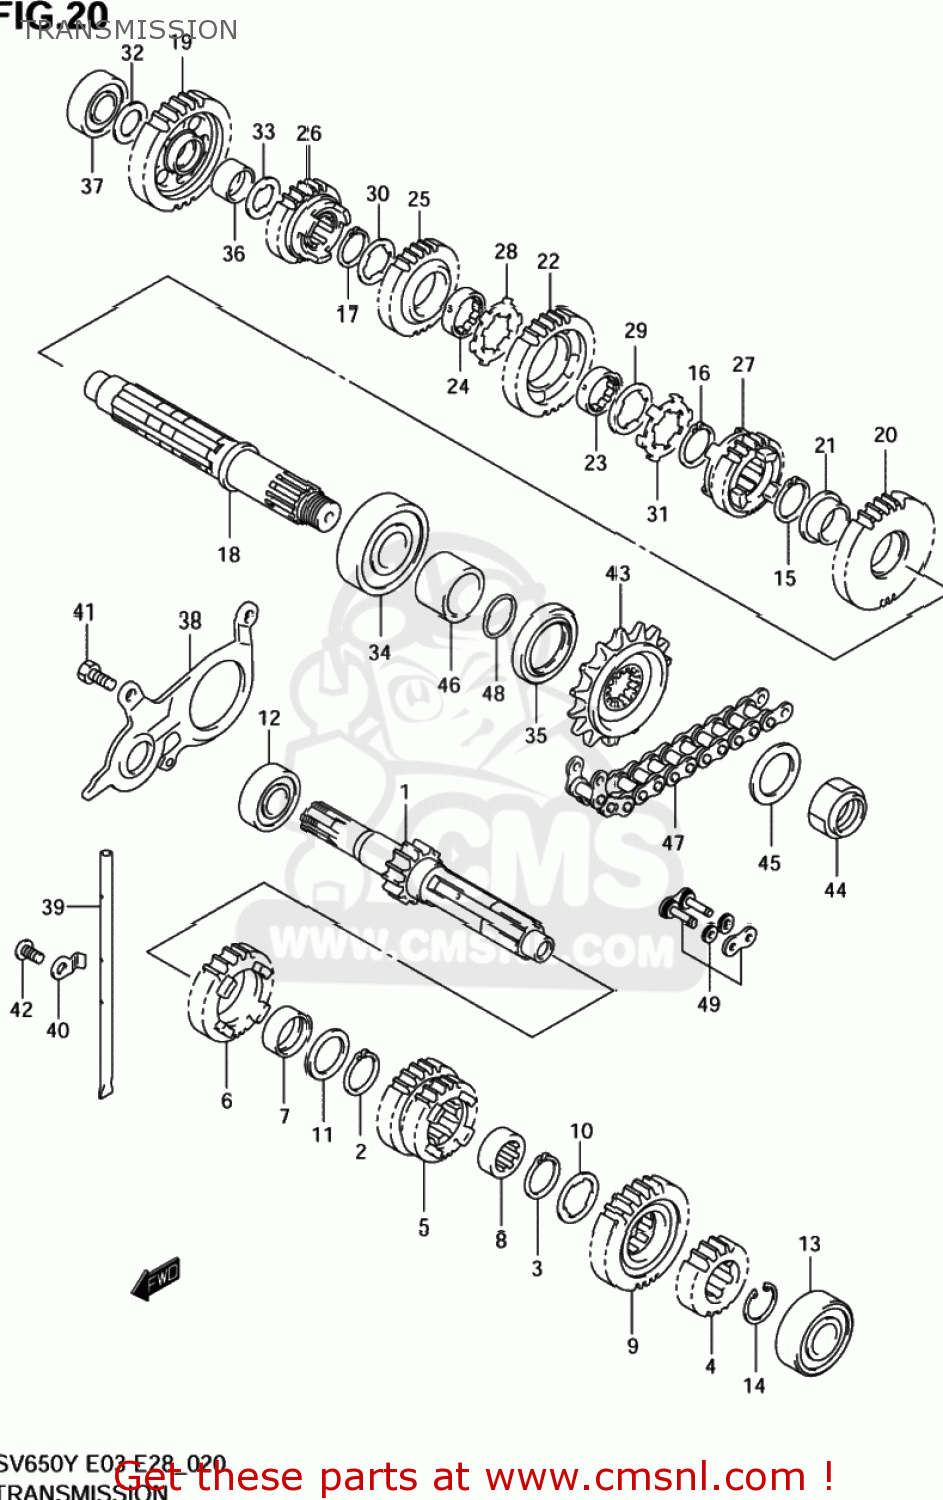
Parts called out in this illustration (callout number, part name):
1	SHAFT,COUNTER(NT:13)
2	CIRCLIP
3	CIRCLIP
4	GEAR,SECOND DRIVE (NT:18)
5	GEAR,3RD & 4TH
6	GEAR,FIFTH DRIVE (NT:26)
7	BUSH
8	BUSH,6TH DRIVE GEAR
9	GEAR,6TH DRIVE(NT:27)
10	WASHER,LOCK
11	SHIM(25X34X1)
12	BEARING(17X40X12)
13	BEARING 20X52X15
14	CIRCLIP
15	CIRCLIP
16	CIRCLIP
17	CIRCLIP
18	SHAFT,DRIVE
19	GEAR,1ST DRIVEN(NT:32)
20	GEAR,SECOND DRIVEN (NT:32)
21	BUSH
22	GEAR,3RD DRIVEN(NT:29)
23	BUSH,DRIVEN GEAR
24	BUSH,DRIVEN GEAR
25	GEAR,4TH DRIVEN(NT:27)
26	GEAR,FIFTH DRIVEN (NT:25)
27	GEAR,SIXTH DRIVEN (NT:23)
28	WASHER,LOCK
29	WASHER,LOCK
30	WASHER,LOCK
31	WASHER
32	SHIM(17X28X1)
33	SHIM(20X30X1)
34	BEARING(25X62X17)
35	SEAL,OIL(36X50X6)
36	BUSH(20X24X13)
37	BEARING(17X40X12)
38	RETAINER,DRIVESHAFT O
39	GUIDE,T/M OIL
40	RETAINER,TRANSMISSION OIL
41	BOLT
42	SCREW
43	SPROCKET,ENGINE(NT:15)
44	NUT
45	WASHER,LOCK
46	SPACER,ENGINE SPROCKET
47	CHAIN,DRIVE(DID525V9,110L)
48	O RING(D:2.4,ID:23.7)
49	JOINT SET,CHAIN
